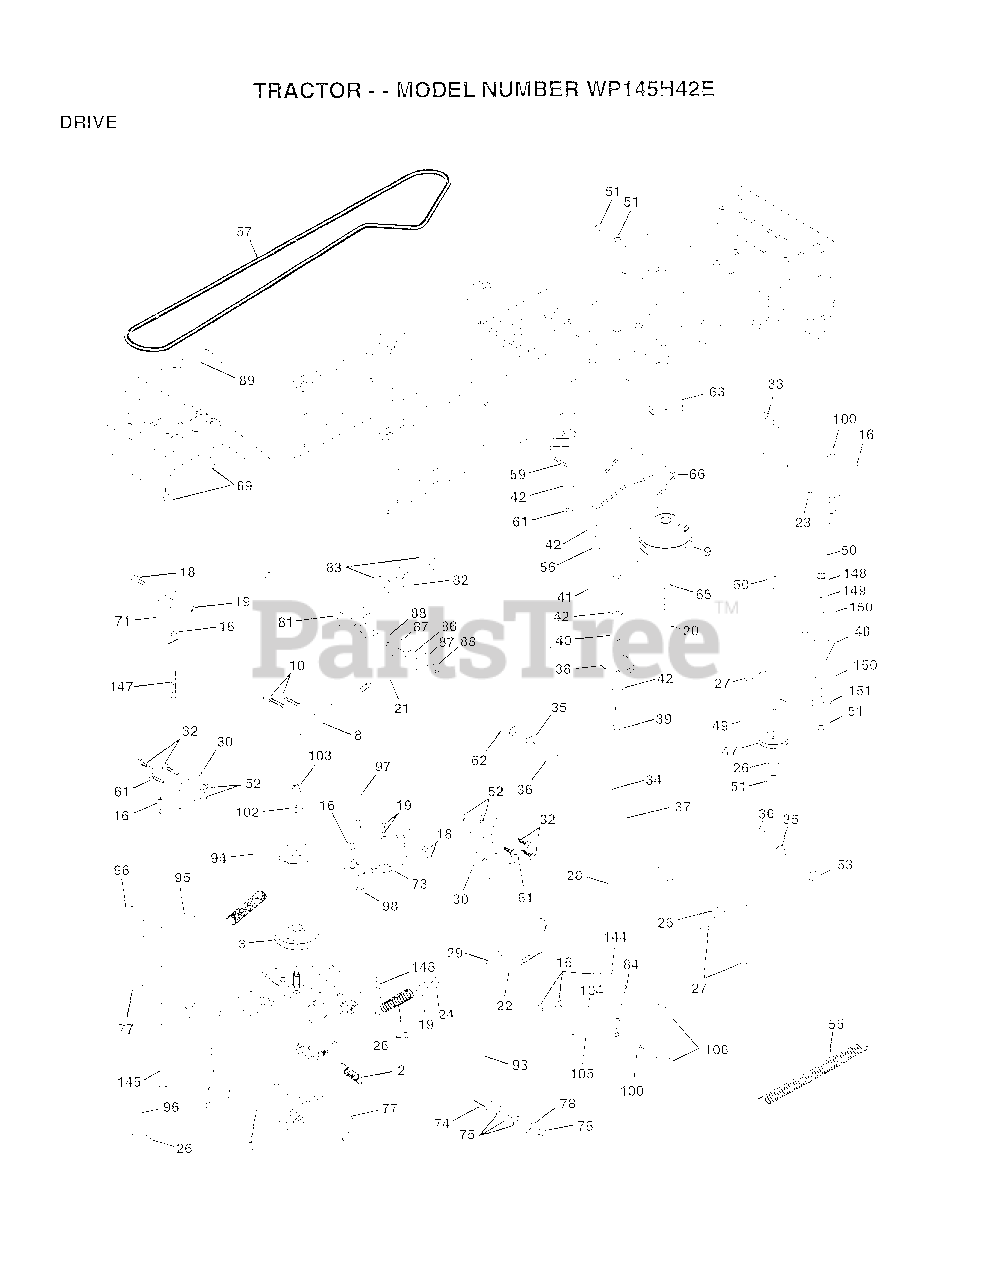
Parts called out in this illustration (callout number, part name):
2	SPRING RET BRAKE
3	PULLEY.TRANSAXLE
8	ROD SHIFT FEND LT
9	CLUTCH.ELECT.EVX.
10	PIN COTTER 1/8
16	NUT
18	BOLT
19	NUT
20	BOLT.7/16-20X4.25
21	KNOB T (1/2-HOLE)
22	ROD.BRAKE.HYDRO.
23	BRACKET.CLUT.MTG.
24	NUT
25	SPRING ROD LT
26	WASHER
27	COTTER PIN
28	ROD.BRAKE.PARK.LT
29	PLUNGER CAP T
30	TRANSAXLE MTG BKT
32	BOLT
33	BOLT
34	SHAFT ASM-PEDAL F
35	NYLON BEARING
36	WASHER LT
38	PULLEY.IDLER.FLAT
39	BOLT
40	SPACER T
42	WASHER
48	BELLCRANK.CLUTCH
49	RETAIN BELT
53	"LINK, CLUTCH T"
55	"SPRING, RETURN LT"
57	V-BELT.GROUND.HYD
59	KEEPER BELT CNTSP
61	SCREW
62	PEDAL COVER T
63	PULLEY.ENGINE
65	LOCKWASHER
66	ENGINE BELT KEEPR
69	SCREW HEXWSH H-L
71	STRAP TORQ LH HYD
72	WASHER
73	"STRAP-TORQUE,RH"
74	SPACER SPLIT
76	E-RING LT
77	SQUARE KEY
78	WASHER
81	SHAFT.ASM.CROSS
82	"SPRING,TORSION"
83	WASHER
84	ROD.TIE
86	BUSHING
87	WASHER D
88	KLIP RING
93	"LINE FUEL HYD 4"""
94	"FAN 7"" HYDRO"
97	BOLT KEEPER RH
98	NUT
100	WASHER M
102	WASHER BELLEVILLE
104	ARM CONTROL HYDRO
105	SCREW CAP 5/16-18
106	BOLT
144	WASHER
145	BOLT.HEX.FLGHD
146	BOLT.HEX.FLGHD.
147	BOLT.HEX.FLGHD
149	SPACER RETAINER
150	BUSHING.NYLON
151	WASHER
